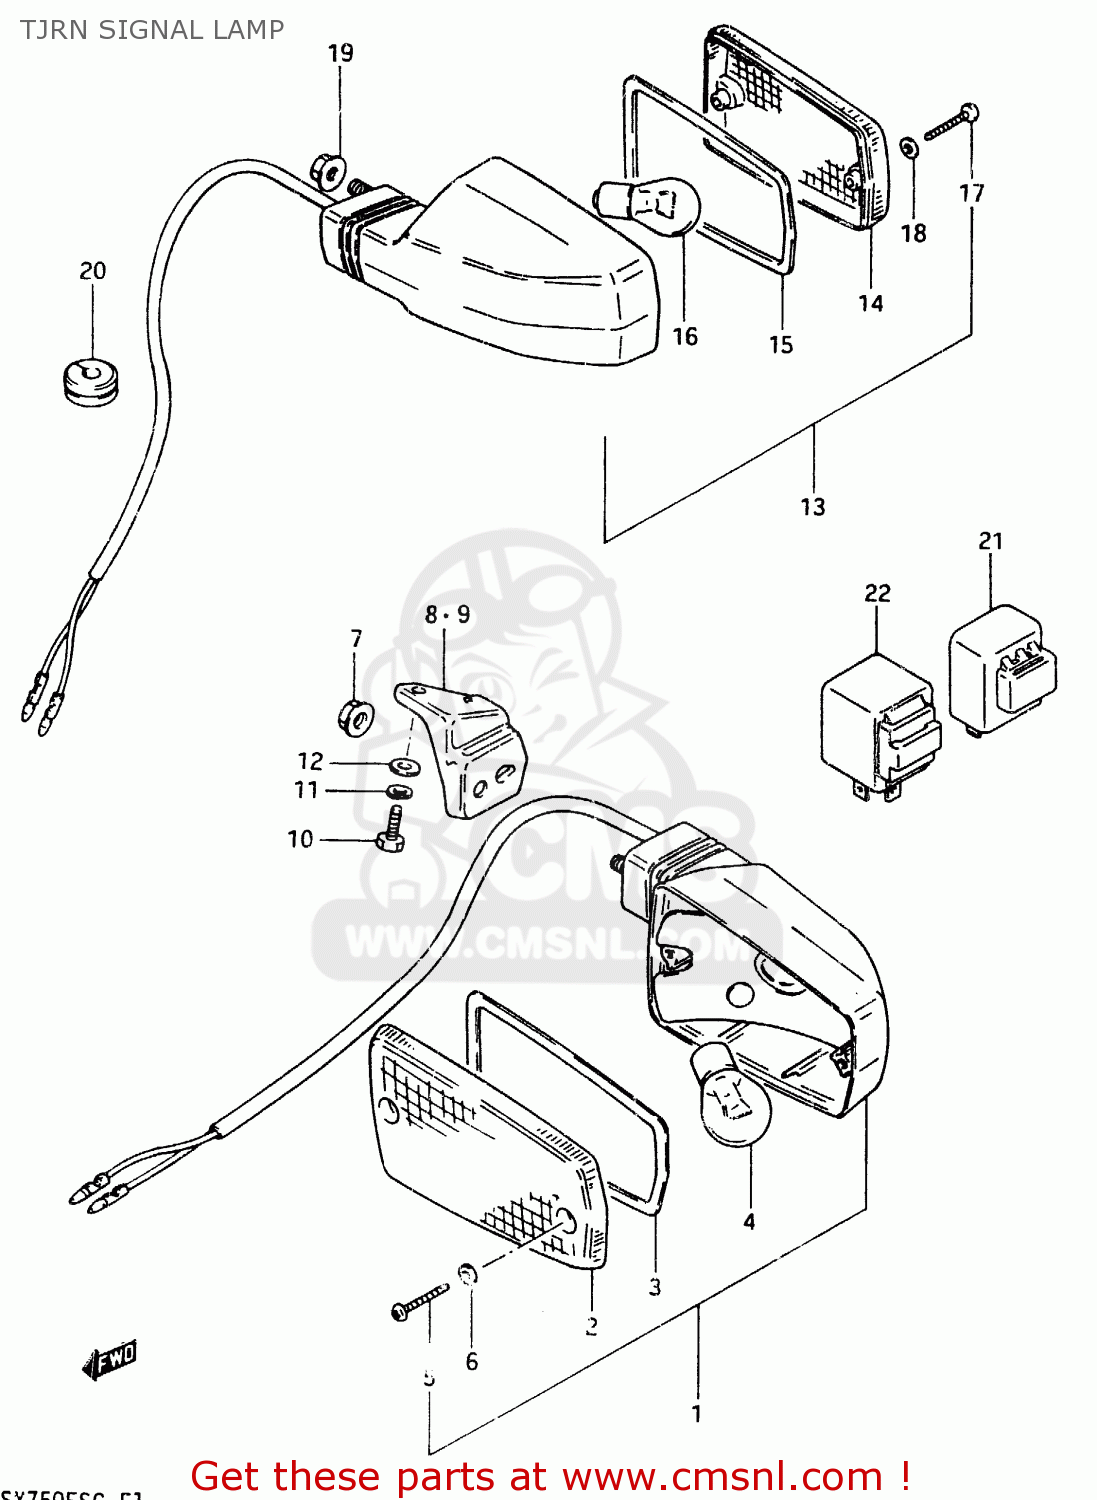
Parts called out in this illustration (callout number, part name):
1	LAMP ASSY,FR TURN SIGNAL
2	LENS
3	GASKET (NAS)
4	BULB(12V21W)
5	SCREW
6	GASKET (NAS)
7	NUT
8	BRACKET,FRONT TURN SIGNAL
9	BRACKET,FRONT TURN SIGNAL
10	BOLT
11	WASHER,LOCK,8.
12	WASHER
13	LAMP ASSY REAR
14	LENS
15	GASKET (NAS)
16	BULB(12V21W)
17	SCREW
18	GASKET (NAS)
19	NUT
20	GROMMET
21	RELAY ASSEMBLY,TURN SIGNAL
22	RELAY ASSY,TUR
